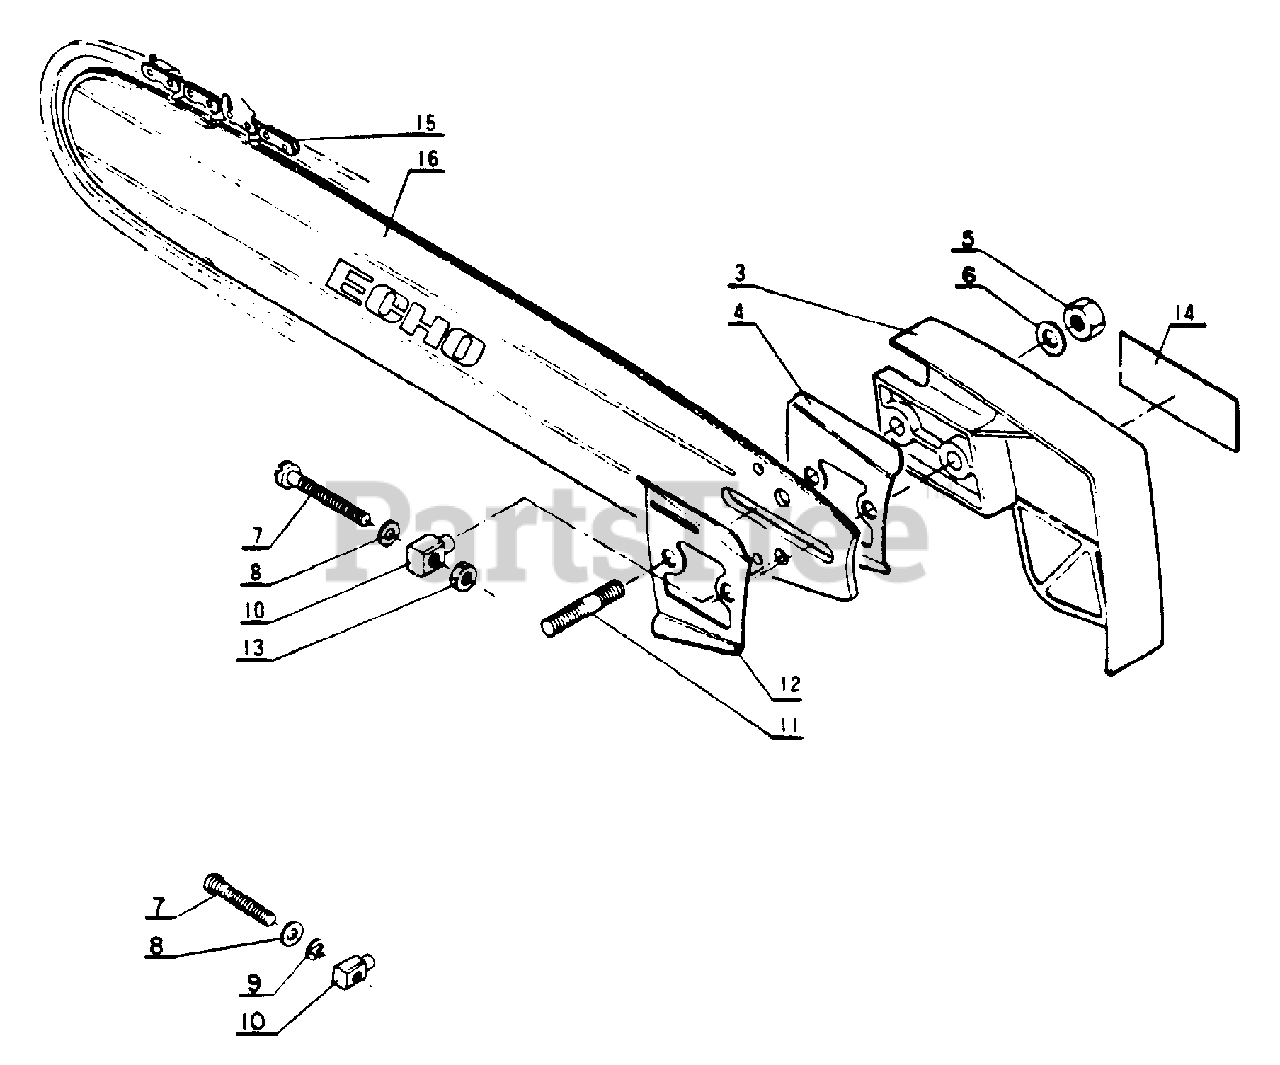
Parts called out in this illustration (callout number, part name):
3	GUARD, SPROCKET
4	PLATE, GUIDE - OUTER
6	WASHER - 8
7	SCREW, TENSIONER
8	WASHER - 5
9	RING, RETAINING
10	TENSIONER, CHAIN
11	STUD, GUIDE BAR
12	PLATE, GUIDE - INNER
13	LOCKNUT - 5
14	Echo plate
15	CHAIN, SAW
16	GUIDE BAR
